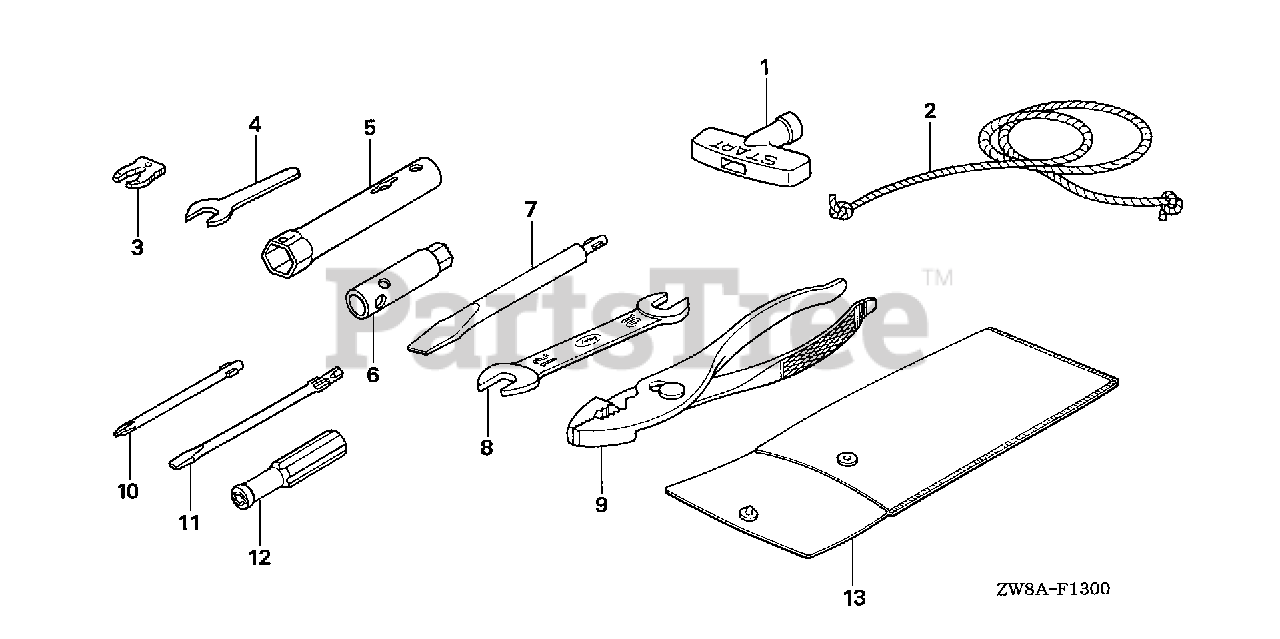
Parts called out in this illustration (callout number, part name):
1	GRIP, STARTER
1	KNOB, RECOIL SRARTER
2	ROPE, RECOIL STARTER (1300MM)
3	CLIP, EMERGENCY LOCK
4	SPANNER (8MM) (NOT AVAILABLE)
5	WRENCH, SPARK PLUG
6	WRENCH, BOX (10MM)
7	SCREWDRIVER, CHECK BOLT
8	SPANNER (10X12)
9	PLIERS (135) (KOWA)
9	PLIERS (135)
10	DRIVER 1, PLUS SCREW (NO.2)
11	DRIVER 3, MINUS SCREW (NO.2)
12	GRIP, SCREW DRIVER
13	BAG, TOOL (160MM)
